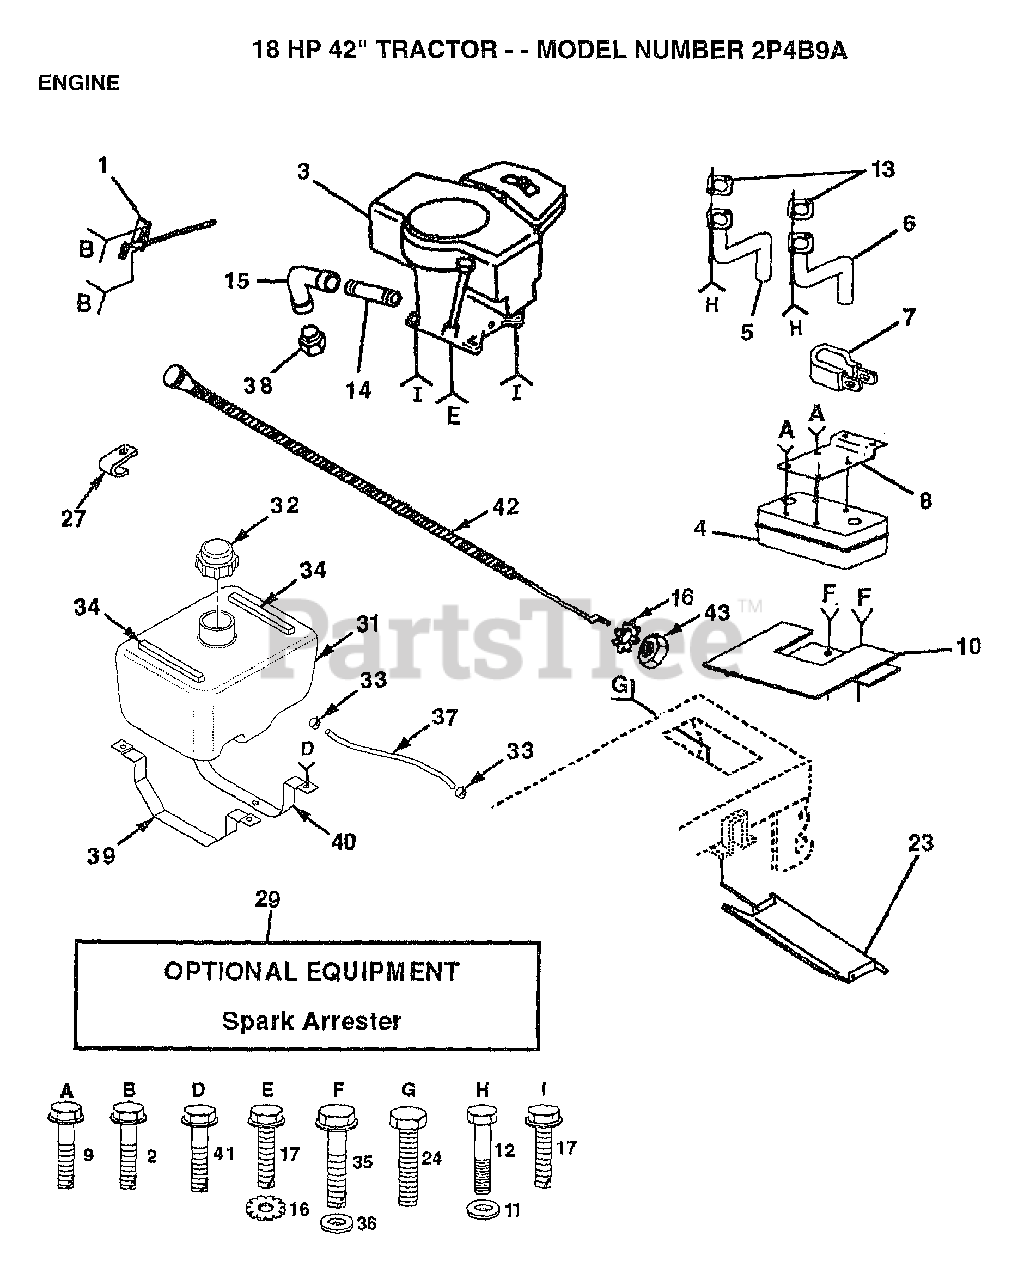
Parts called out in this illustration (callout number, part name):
2	SCREW LT
5	EXHAUST ASM LH
7	CLAMP.TUBE.DBL.EN
8	BRACKET MUFFLER
9	SCREW ST
10	SHIELD HEAT LT
14	PIPE NIPPLE LT
15	ELBOW
16	LOCKWASHER
17	SCREW LT
23	HEAT SHIELD
24	SCREW
27	"CLIP,INSULATOR"
31	TANK FUEL 1.9 NAT
32	CAP ASM FUEL
33	HOSE CLAMP
34	"STRIP,FORM"
35	SCREW
36	WASHER
37	FUEL LINE T
39	"STRAP,TANK "
40	"STRAP,TANK"
41	SCREW
42	CONTROL.CHK.26.38
